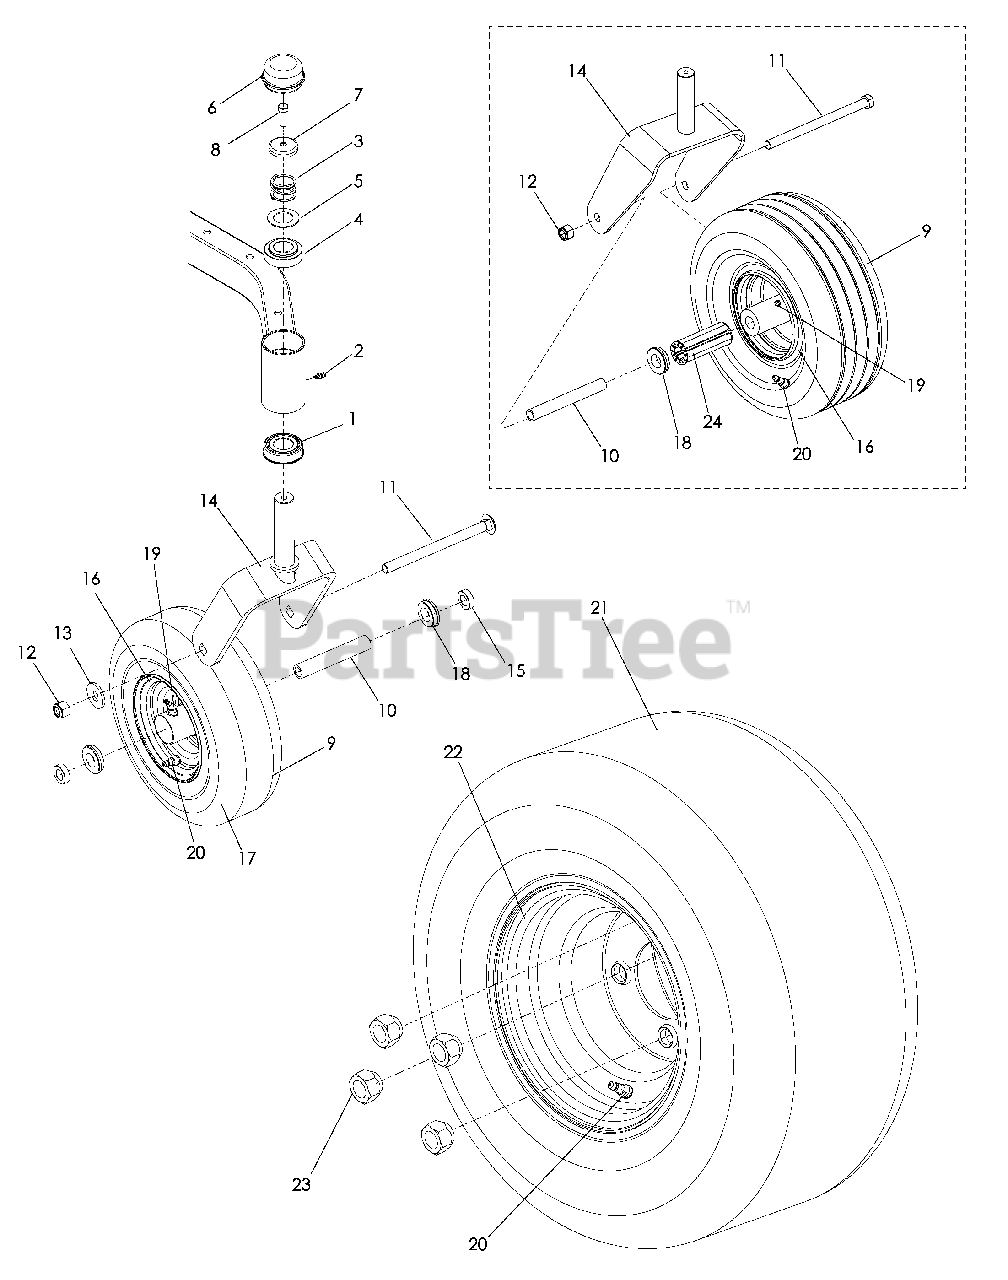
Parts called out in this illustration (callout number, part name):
1	BEARING, FLANGED
2	ZERK 3/16 DRIVE
3	SPRING, CASTER
4	BUSHING, CASTER
6	GREASE CAP
7	PLUG, CASTER
8	HCS 5/16-18 x 1
9	CASTER TIRE ASSM EZ4824, EZ5226
10	SPACER EZ4824, EZ5226
11	RHSNB ½-13 x 6½ EZ4824, EZ5226
12	NUT ½ HEX NYLOC
13	WASHER ½ FLAT
14	YOKE EZ4824, EZ5226
15	SPACER 5/16 EZ4824, EZ5226
16	RIM EZ4824, EZ5226
17	CASTER TIRE, 410/350 4 PLY EZ4824, EZ5226
18	BEARING, FLANGED
19	ZERK EZ4824, EZ5226
20	VALVE STEM
21	TIRE, REAR ASSM 22 x 9.5 EZC4824, EZ4824K, EZ5221, EZ5224, EZ6124
22	RIM 8 x 7 w/ .8" OFFSET EZ5226, EZ4824
23	NUT, LUG ½
24	BEARING EZC4824, EZ4824K, EZ5221, EZ5224, EZ6124
